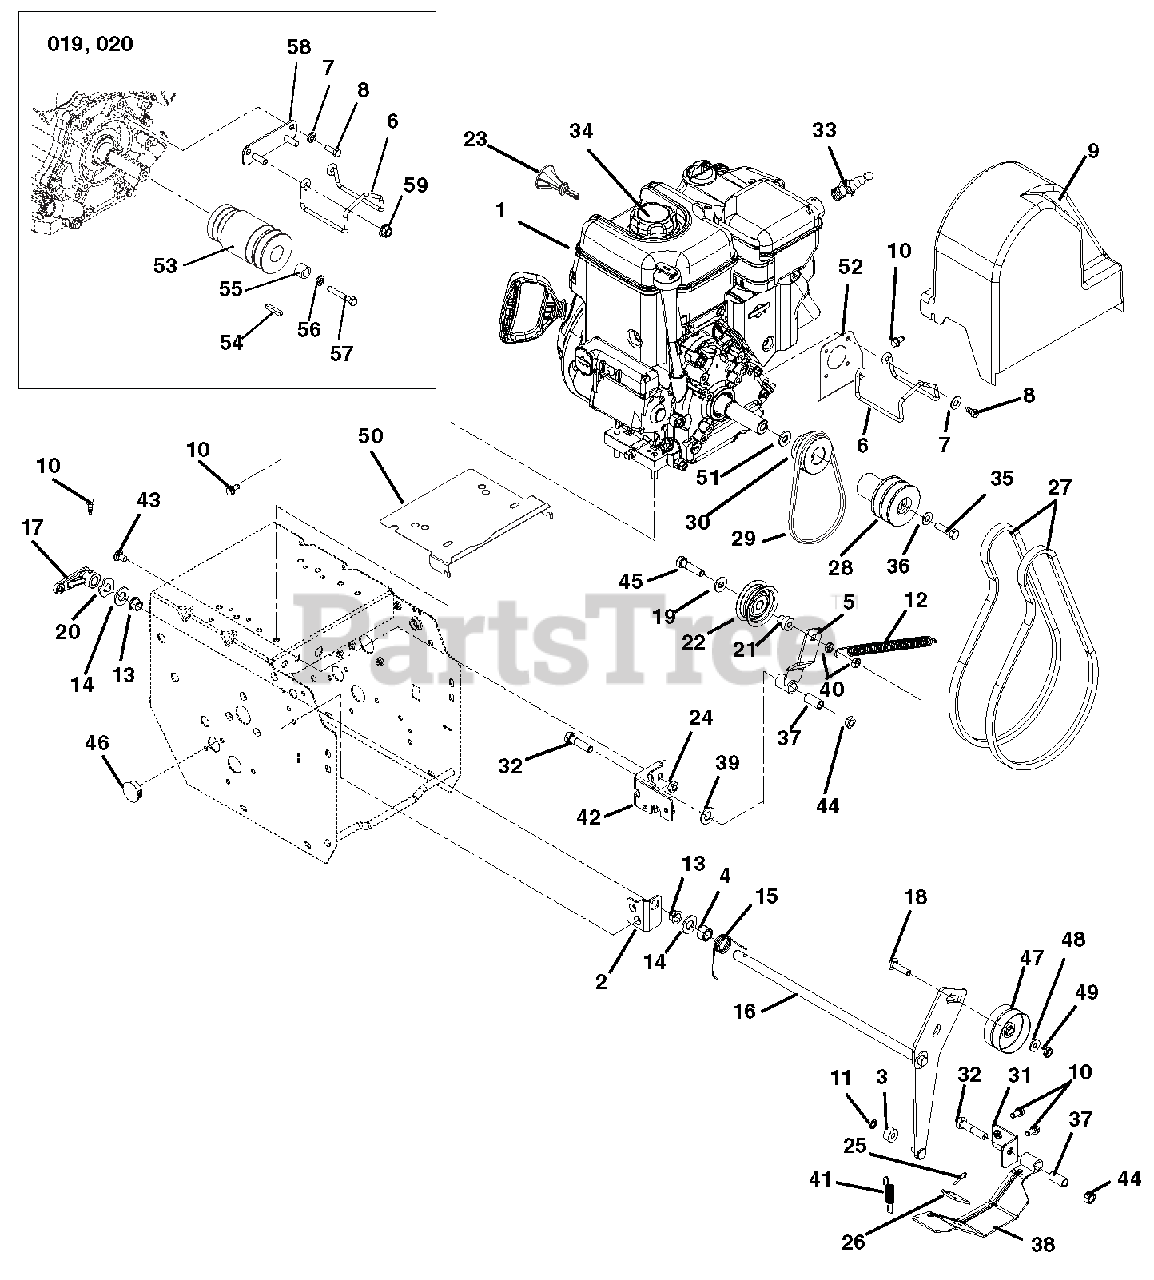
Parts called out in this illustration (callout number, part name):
1	ENGINE, BRIGGS SNOW 1150, 120V
1	ENGINE, BRIGGS SNOW 1450, 120V
1	ENGINE, BRIGGS SNOW 1650, 120V
1	ENGINE, SUBARU SX21 SNOW RECL
1	ENGINE, SUBARU SX30 SNOW 120V
1	ENGINE, BRIGGS SNOW 1150, 240V
1	ENGINE, BRIGGS SNOW 1450, 240V
1	ENGINE, BRIGGS SNOW 1650, 240V
2	BRACKET, MOUNT - IDLER ARM
3	BSHG,SLV .265 X .625 X .375
4	BSHG-SLV .510X.751X.475
5	WELDMENT, TRACTION IDLER ARM
6	FINGER, BELT
7	WSHR-LK .312X.097 HVY YWZC
8	BLT-HEX .31-24X.75 YWZC GR5
9	PLZ SEE SERVICE LETTER #L-2166
9	BELT COVER
10	SCR-TAP .25-20X.50 HWH TR YWZ
11	RG-RTNG-EXT .250X.010
12	SPRING, SWIVEL HOOK EXTENSION
13	BUSHING, POLYLINER-.50 SPLIT
14	WSHR-FL-STL.531X1.00X.063 YWZC
15	SG-TORS .075 X .955
16	WELDMENT, ATTACHMENT IDLER ARM
17	ARM, CLUTCH - ATTACHMENT
18	@BLT-RHDSSQNK .38-16X1.75 G5YZ
19	@WSHR-FL-STL.38X.875X.083 YWZC
20	WSHR-WAVE .50X.75X.015 .13FRHT
21	SPCR, BRG .315X.50X.688X.281
22	IDLER
23	KEY, PUSH/PULL BRIGGS
23	KEY, PUSH/PULL SUBARU
24	@NUT-LK-TOP-FLG .31-18 YWZC
25	RVT-POP .187 YZ
26	PAD, BRAKE
27	V-BELT, HA-RAW EDGE (SET)
28	SHEAVE, ATTACHMENT 2-GRV
29	V-BELT, 3L-WRAPPED
30	SHEAVE, DRIVE
31	BRACKET, BRAKE MOUNT
32	@BLT-HEX .38-16X1.75 GR5 YWZC
33	PLUG, SPARK
33	PLUG, SPARK SUBARU
34	CAP, FUEL - BRIGGS & STRATTON
34	CAP, FUEL SUBARU
35	BLT-HEX .38-24X2.25 YWZC GR5
36	@WSHR-LK .38X.094 REG YWZC
37	BSHG-SLV .385X.500X1.045
38	BRAKE ARM W/PAD
39	@WSHR-FL-STL.406X.812X.065 YWZ
40	@NUT-LK-CTR-JAM .31-18 YWZC
41	SPRING-EXT .047 X .438 X 1.85
42	WELDMENT, FRAME BRACKET
43	@BLT-RHDSSQNK .31-18X.62 G5YZ
44	@NUT-LK-TOP-FLG .38-16 YWZC
45	@BLT-HEX .31-18X1.50 GR5 YWZC
46	PLUG, HOLE - .875" NYLON
47	IDLER, FLAT 2.75" DIA
48	@WSHR-FL-STL.38X.875X.083 YWZC
49	@NUT-LK-CTR-JAM .375-16 YWZC
50	BAFFLE,ENGINE,SMALL BLOCK
51	BAFFLE, BRIGGS MDL 20/21 WATER
51	WSHR-FL-STL- 1.062X2.0X.134 YZ
52	BAFFLE, PRIMARY WATER
53	SHEAVE, ENGINE - SUBARU ES21
53	SHEAVE, ENGINE - SUBARU ES30
54	KEY-SQ .188X1.50X.188
54	KEY .25X.25X2.25
55	BUSHING, SLEEVE
55	BSHG-SPACER .47X1.25X.50
56	WSHR-LK .312X.097 HVY YWZC
56	@WSHR-LK .44X.109 REG YWZC
57	@BLT-HEX .31-24X2.50 GR5 YWZC
57	BLT-HEX .44-20X1.50 G5 YZ EP80
58	PLATE, BELT FINGER MOUNT
59	@NUT-LK-TOP-FLG .31-18 YWZC
